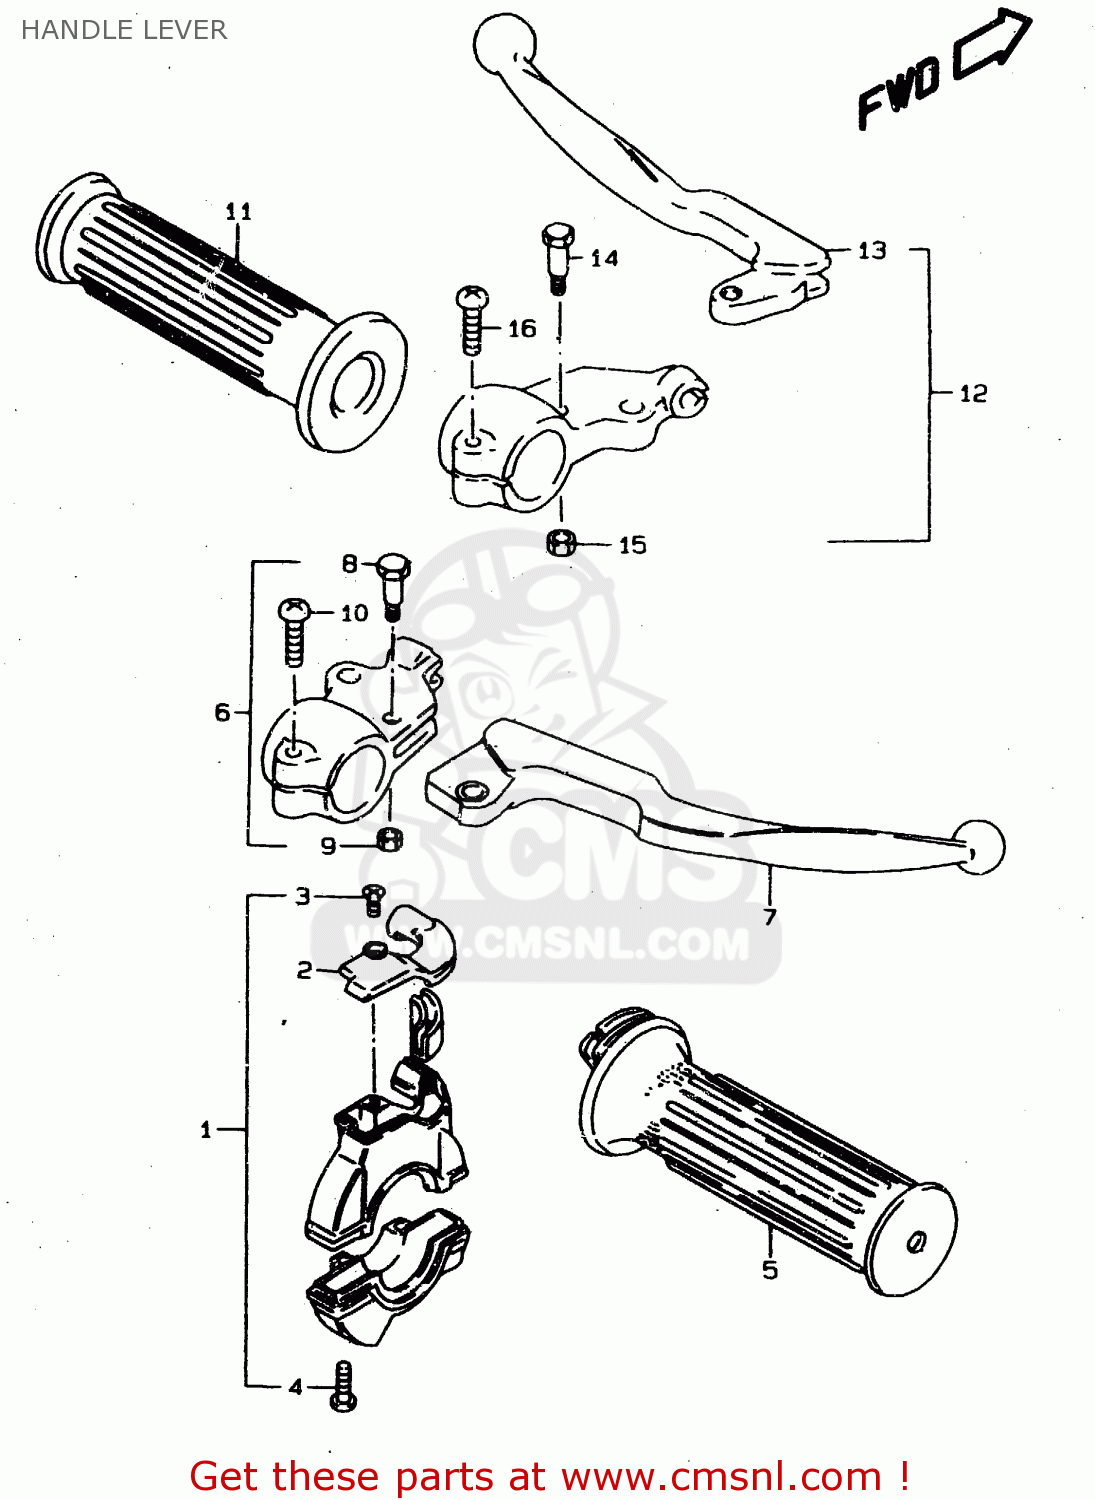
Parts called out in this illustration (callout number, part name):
1	CASE ASSY,THROTTLE
2	COVER,THROTTLE CASE
3	SCREW,UPPER
4	SCREW
5	GRIP,THROTTLE
6	LEVER ASSY,BRAKE
7	LEVER,BRAKE
8	SCREW
9	NUT
10	SCREW, 6X20
11	GRIP,L
12	LEVER ASSY,CLUTCH
13	LEVER,CLUTCH
14	SCREW
15	NUT
16	SCREW, 6X20
